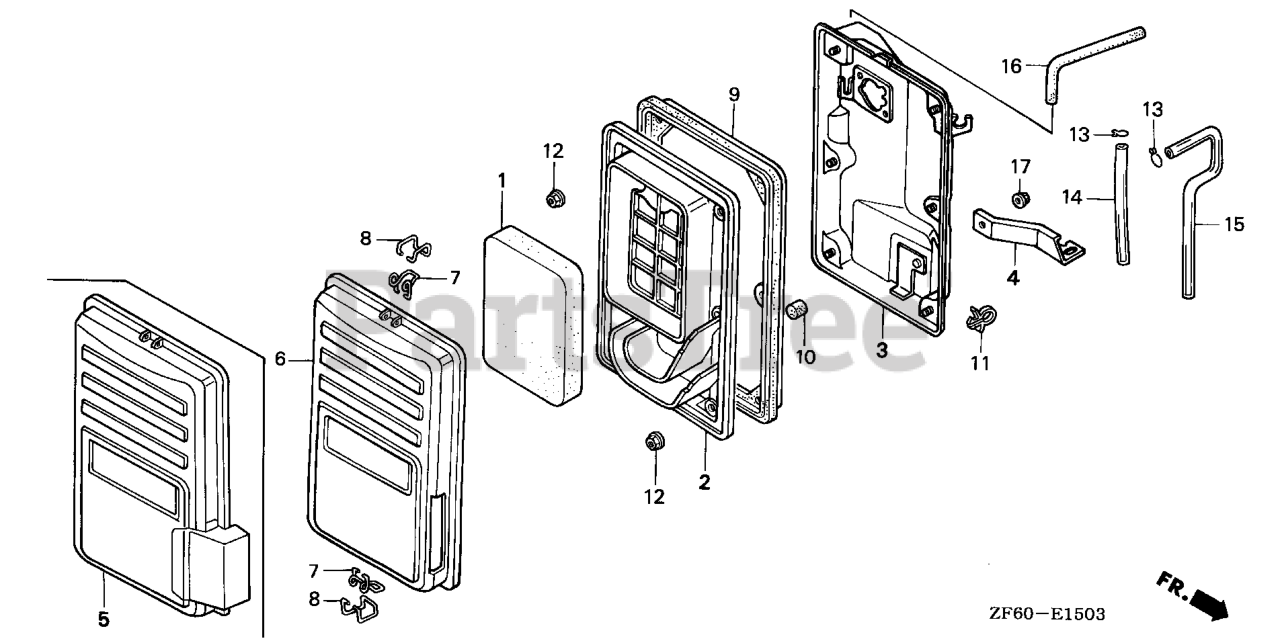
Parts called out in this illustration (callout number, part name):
1	ELEMENT, AIR CLEANER
2	SEPARATOR, AIR CLEANER
3	HOUSING, AIR CLEANER
4	STAY, AIR CLEANER
6	COVER, AIR CLEANER
7	CLIP A, AIR CLEANER WIRE
8	CLIP B, AIR CLEANER WIRE
10	FILTER, DRAIN TUBE
12	NUT, FLANGE (5MM)
16	TUBE, BREATHER
17	NUT, FLANGE (6MM)
